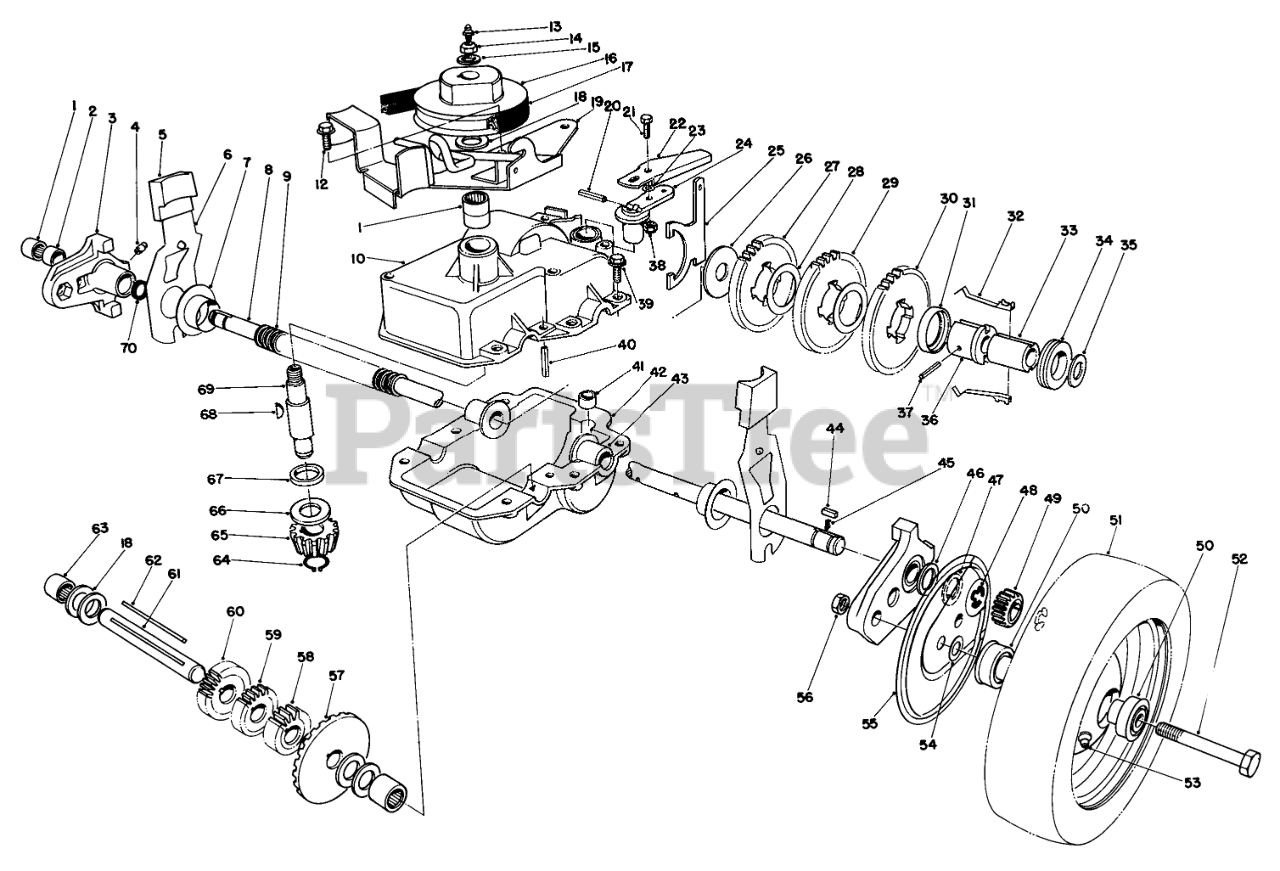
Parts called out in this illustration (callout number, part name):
1	BEARING-NEEDLE
2	BUSHING
3	Pivot Arm Assembly (Incl. Ref. #1-2, 4 & 70)
4	FITTING-GREASE
5	KNOB-ARM
6	SPRING ARM ASM
7	CAP-END
8	Output Shaft
9	CONDUIT-CONVOLUTED, SPLIT
10	Case-Upper
12	SCREW
13	FITTING-GREASE
14	NUT-HEX
15	WASHER-FLAT
16	PULLEY
17	V-BELT
18	WASHER-THRUST
19	BELT GUIDE BRKT W A
20	PIN-COIL
22	Cover-Shift Lever
23	WASHER-FLAT
24	LEVER-SHIFT
25	Shift Yoke
26	WASHER
27	GEAR-38T
28	WASHER
29	GEAR-42T
31	KEY RETAINER
32	Key
33	SLEEVE
34	COLLAR-SHIFT
35	WASHER-PLAIN
36	Body-Sleeve
37	PIN-SPIROL
38	NUT-LOCK, NI
39	SCREW-HWH, THREAD ROLL
40	ROLL PIN 3/16 X 1 IN
41	BUSHING-YOKE
42	Case-Lower
43	BUSHING
44	KEY RECTANGULAR
45	SPRING-COMPRESSION
46	THRUST WASHER
47	KEYED WASHER
48	RING-RETAINING
49	GEAR-PINION
50	WHEEL BRG
51	Wheel & Tire Assembly (Incl. Ref. #50 & 53)
52	SCREW-HH
53	FITTING-GREASE
54	WASHER
55	WHEEL COVER
56	NUT-LOCK, CONE
57	BEVEL GEAR
58	GEAR-12T
59	GEAR-14T
60	GEAR-18T
61	Shaft-Intermediate
62	Key Square
63	BEARING-NEEDLE, CLOSED
64	RING-RETAINING
65	PINION-BEVEL
66	WASHER-THRUST
68	KEY-WOODRUFF
69	Shaft Input
